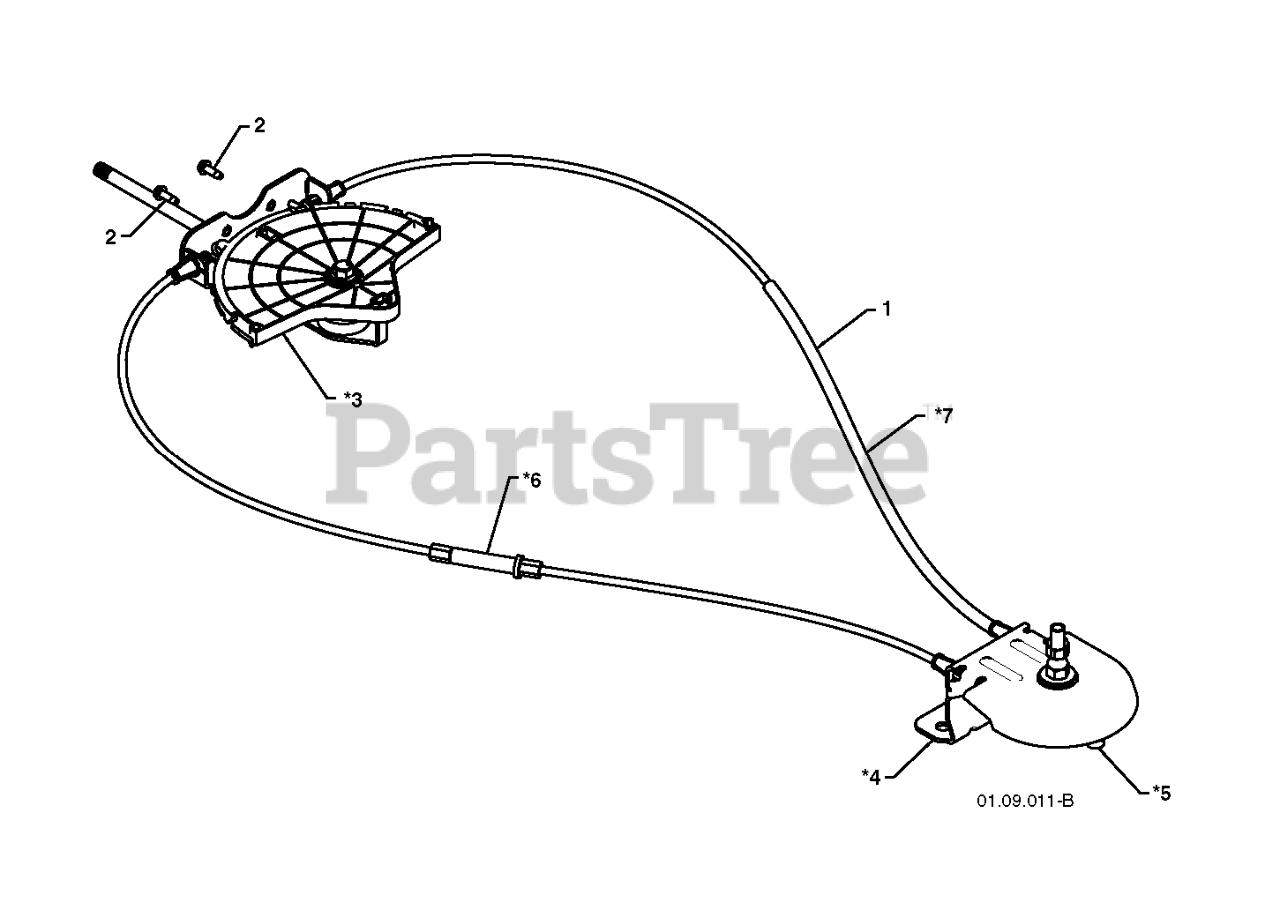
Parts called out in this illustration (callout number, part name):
1	RB LEVER.CABLE.ASM.ROTATR.PLTD
2	SCREW #10-24 X 5/8
3	CHUTE.ROT.HEAD.SERVICE
4	SNOW.PIVOT.BRKT.GRY.SERVICE
5	SNOW.PIVOT.PULLY
6	SNOW.CABLE.ASM.ADJUSTABLE.GRAY
7	SNOW.CABLE.ASM.SERVICE
